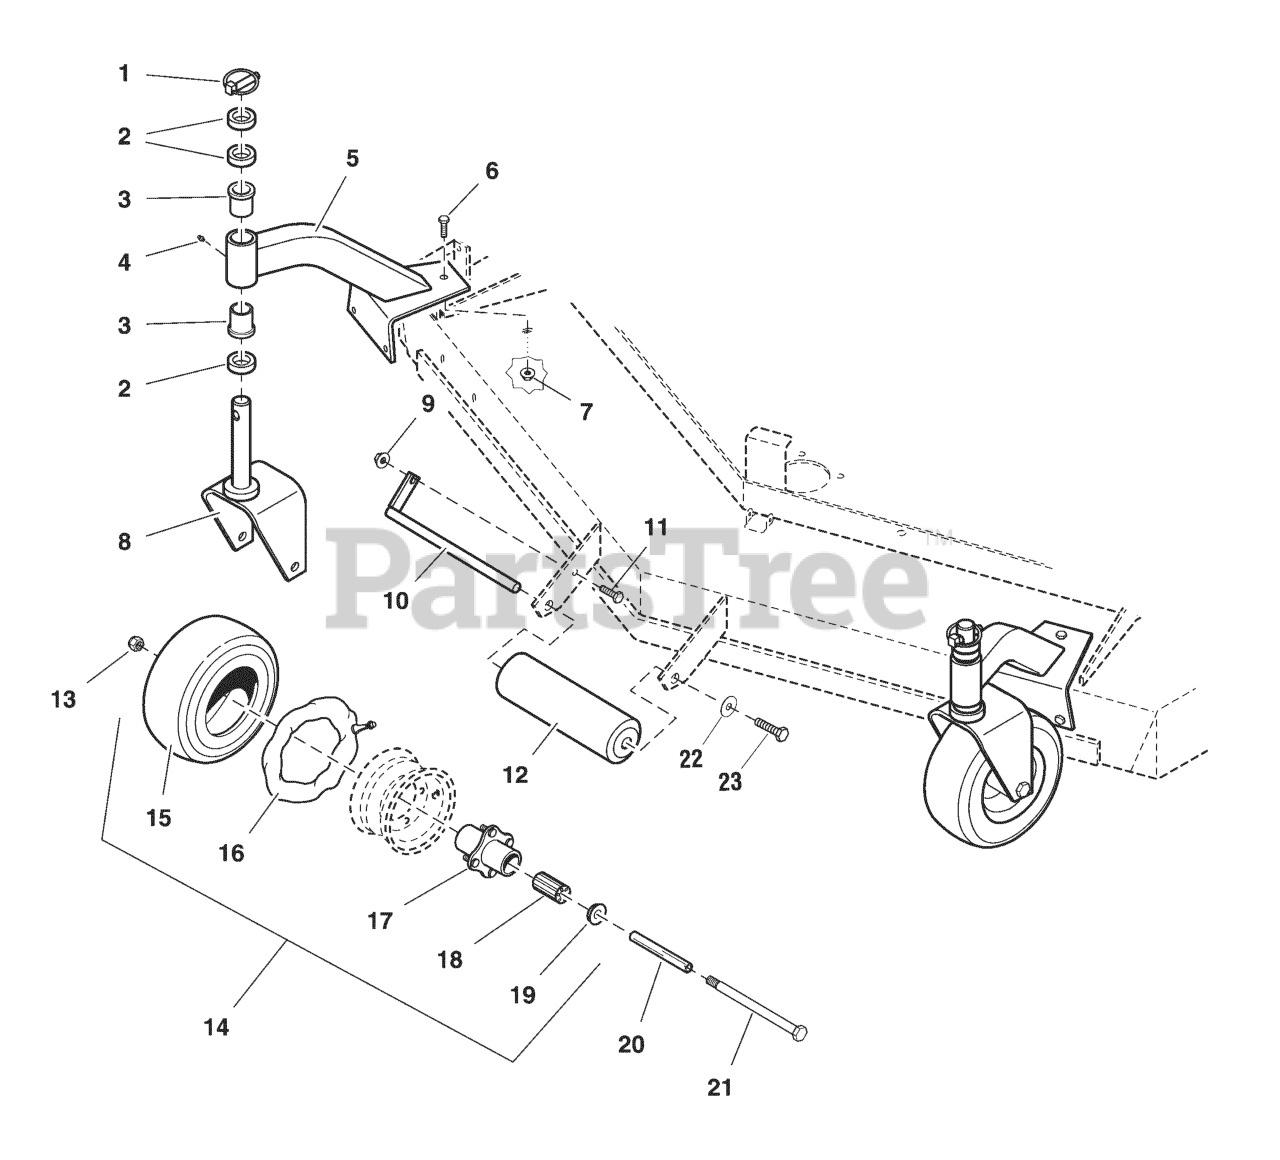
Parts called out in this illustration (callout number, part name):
1	PIN, Lynch
2	SPACER, 1.02 x 1.56 x .50
3	BUSHING, FLANGE
4	GREASE FITTING
5	CASTER MOUNT, Complete
6	BOLT, 5/16-18 X 3/4 GD5
7	NUT, 5/16-18 HEX SERRATED FLANGE (LARGE)
8	YOKE, Caster
9	NUT, 3/8-16 Hex Serrated Flange
11	BOLT, 3/8-16 X 3/4" GD5 CZ
12	ROLLER
13	NUT, 1/2-13 HEX NYLON LOCK
14	TIRE ASSM, 9 X 3.5 X 4, SILVER
14	WHEEL & TIRE ASSEMBLY, White, 9 x 3.5 x 4, Complete
15	TIRE, Front, 9 x 3.5 x 4
17	HUB & BEARING ASSEMBLY, Complete, Silver
17	HUB & BEARING ASSEMBLY, Complete, White
18	BEARING, ROLLER 3/4" ID X 3.25" (ONE PER TIRE)(SV)
19	RETAINER, Bearing
20	AXLE, Caster Wheel
21	BOLT, 1/2-13 x 5-1/2
22	WASHER, .390 X 1.50 X .109 YZ
23	BOLT, 3/8-16 X 1" GD5 CZ
